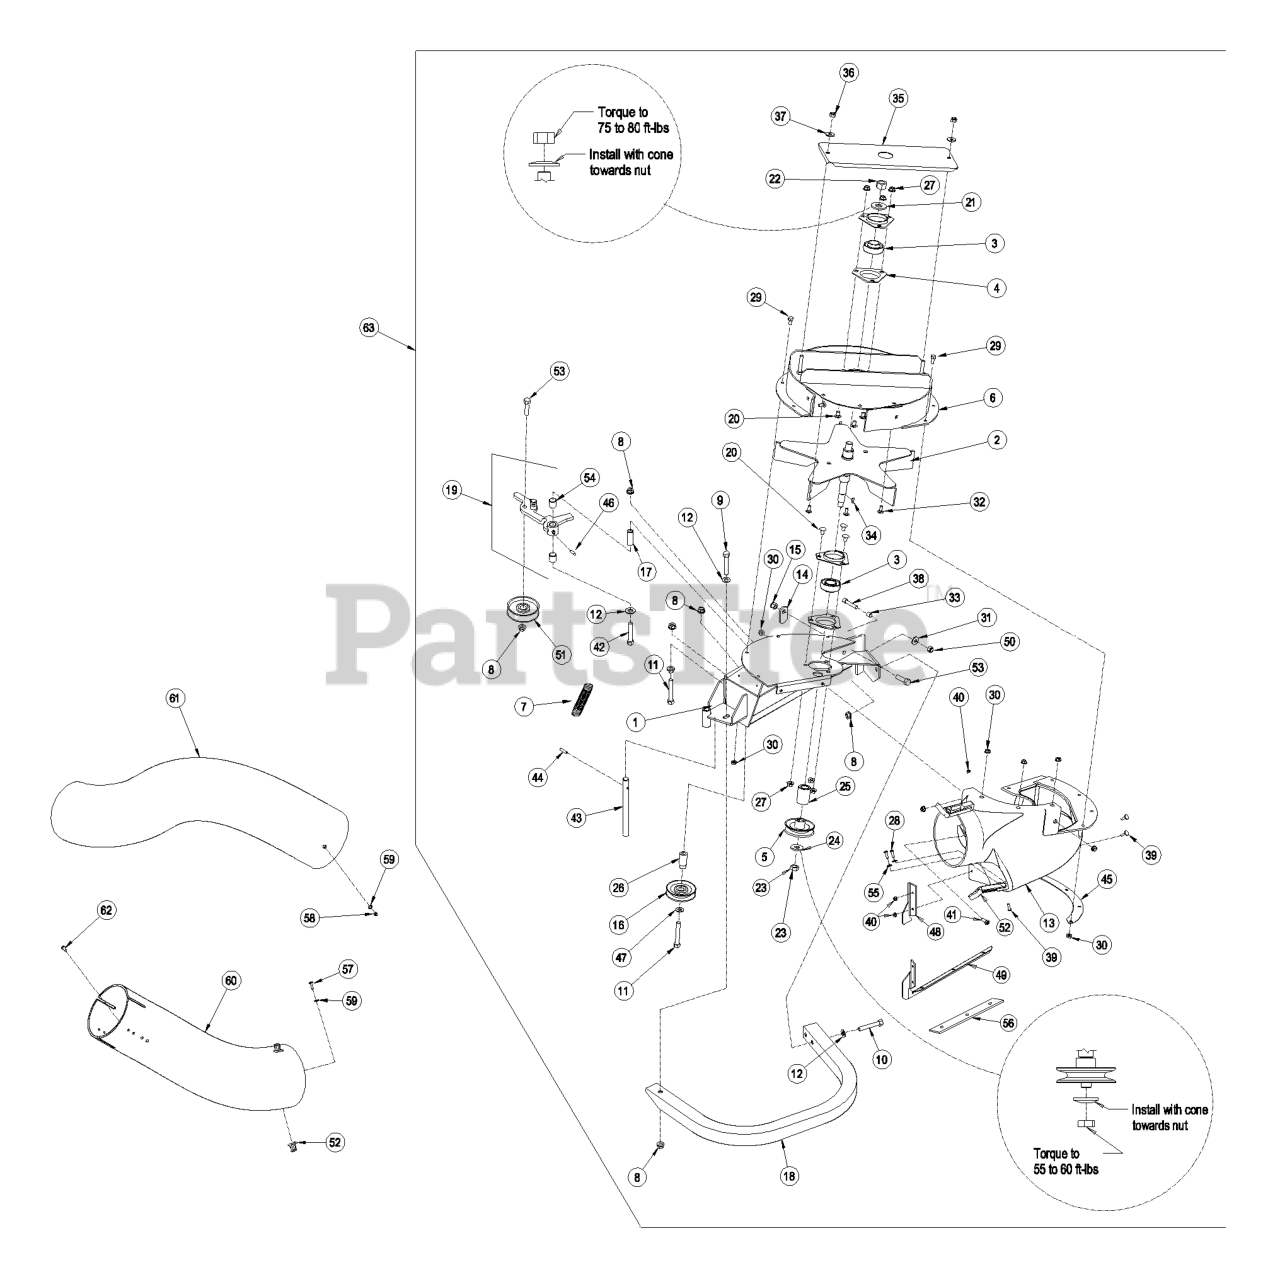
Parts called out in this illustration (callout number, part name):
1	WLD,BLOWER MOUNT
2	IMPELLER
3	BEARING
4	HOUSING-FLANGE
5	SHEAVE-BLOWER
6	ASM, UPPER HOUSING LZUV52
7	SPRING-IDLER
8	NUT-HHF, WHIZ
9	SCREW-HH
10	SCREW-HH
11	BOLT-CARR
12	WASHER-FLAT
13	CHUTE-BLOWER, SMALL
14	LATCH-CATCHER, GRASS
15	NUT-LOCK, NI
16	IDLER-INSIDE
17	BUSHING-PIVOT, IDLER
19	ASM, IDLER ARM - SERVICE
20	SCREW-CARR
21	WASHER-SPRING
22	NUT-HEX
23	NUT-JAM
24	WASHER-SPRING
28	SCREW-PPH
29	SCREW-HH
31	WASHER-SPRING
32	SCREW-CARR
33	BUSHING, LOCATOR
34	KEY-WOODRUFF
35	ASM, BEARING COVER
36	NUT-LOCK, NI
37	WASHER-FLAT
38	SCREW-HSH
39	SCREW-HEAD, TRUSS
42	SCREW-HSBH
43	SHAFT-CATCHER, GRASS
44	PIN-ROLL
45	PLATE-BACKING, BLOWER
46	FITTING-GREASE
47	WASHER-FLAT
48	PLATE, FILLER
49	PLATE, BLOCKER
50	NUT-HEX
51	IDLER-FLAT
52	LATCH DRAW
53	SCREW-HH
54	BUSHING
55	WASHER-FLAT
56	PLATE-REINFORCEMENT
57	SCREW-PPH
58	NUT-LOCK, NI
59	WASHER-FLAT
60	KIT,LOWER TUBE
61	TUBE-UPPER
62	SCREW-HWH
63	ASM, BLOWER LZUV52 - SERV
